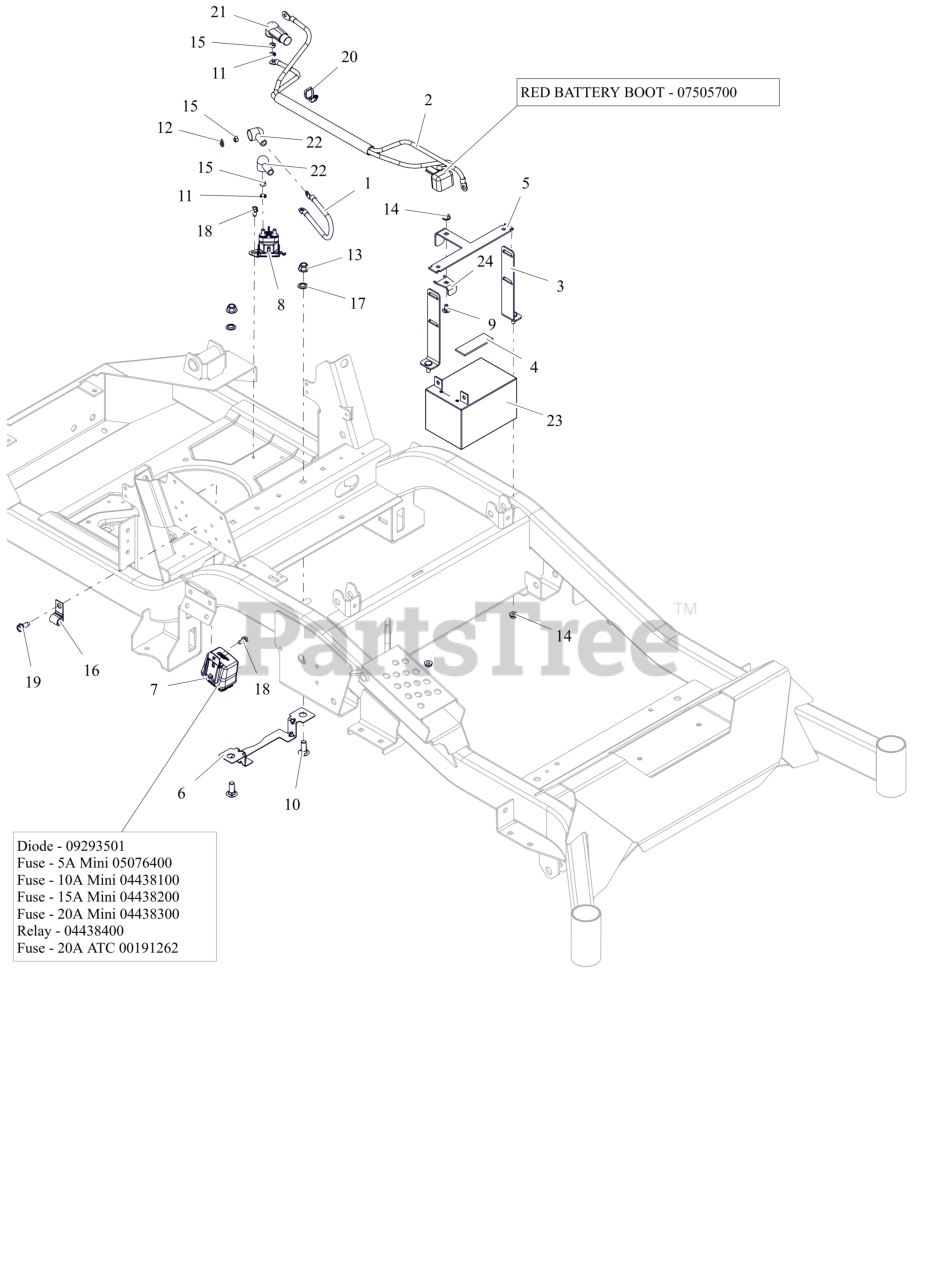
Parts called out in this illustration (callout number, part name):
1	CABLE, POS W/(2)1/4 RING 9.0LG
2	HARNESS, BATTERY HD
2	INSULATOR
3	WMT,BATTERY MOUNT HOLD DOWN
4	PAD,RBR 1.0"X3.0" W/ADHESIVE
5	BRKT, BATTERY TIE DOWN
6	GUARD, ELECTRICAL HARNESS
7	HARNESS, WIRE
7	DIODE, CONNECTOR SHELL
7	FUSE, 5 AMP MINI-ATC
7	FUSE,10 AMP MINI-ATC
7	Fuse, 15 AMP MINI-ATC
7	FUSE,20 AMP MINI ATC
7	RELAY,MICRO5 TERML W/RESISTOR
7	FUSE, 20 AMP BLADE S/O
8	SOLENOID, STARTER (SEALED)
9	BLT, RHSN .25-20X.500 G5 ZCC
10	BLT, RHSN .38-16X1.00 G5 ZCC
11	WSHR,LK-EXT.262X.502X.026 ZCC
12	WSHR,LK-REG .312X.078 ZCC
13	NUT,NYL-FLG .38-16 GF ZCC
14	NUT-LK-TOP-FLG .250-20 GF ZCC
15	NUT-STD M6-1.0 ZCC
16	J-CLAMP
17	NUT-PUSH .38 DIA. PAL ZINC
18	SCR-TAP .25-20X.50 HWH ZCC
19	SCR,TAP .312-18X.75 HWH TR ZCC
20	CABLE TIE W/ TREE (.25 HOLE)
21	BOOT, .65ID POS
22	BOOT, EYELET TERMINAL
23	BATTERY, 12V 12A -190CCA
24	BRKT, BATTERY HOLD
